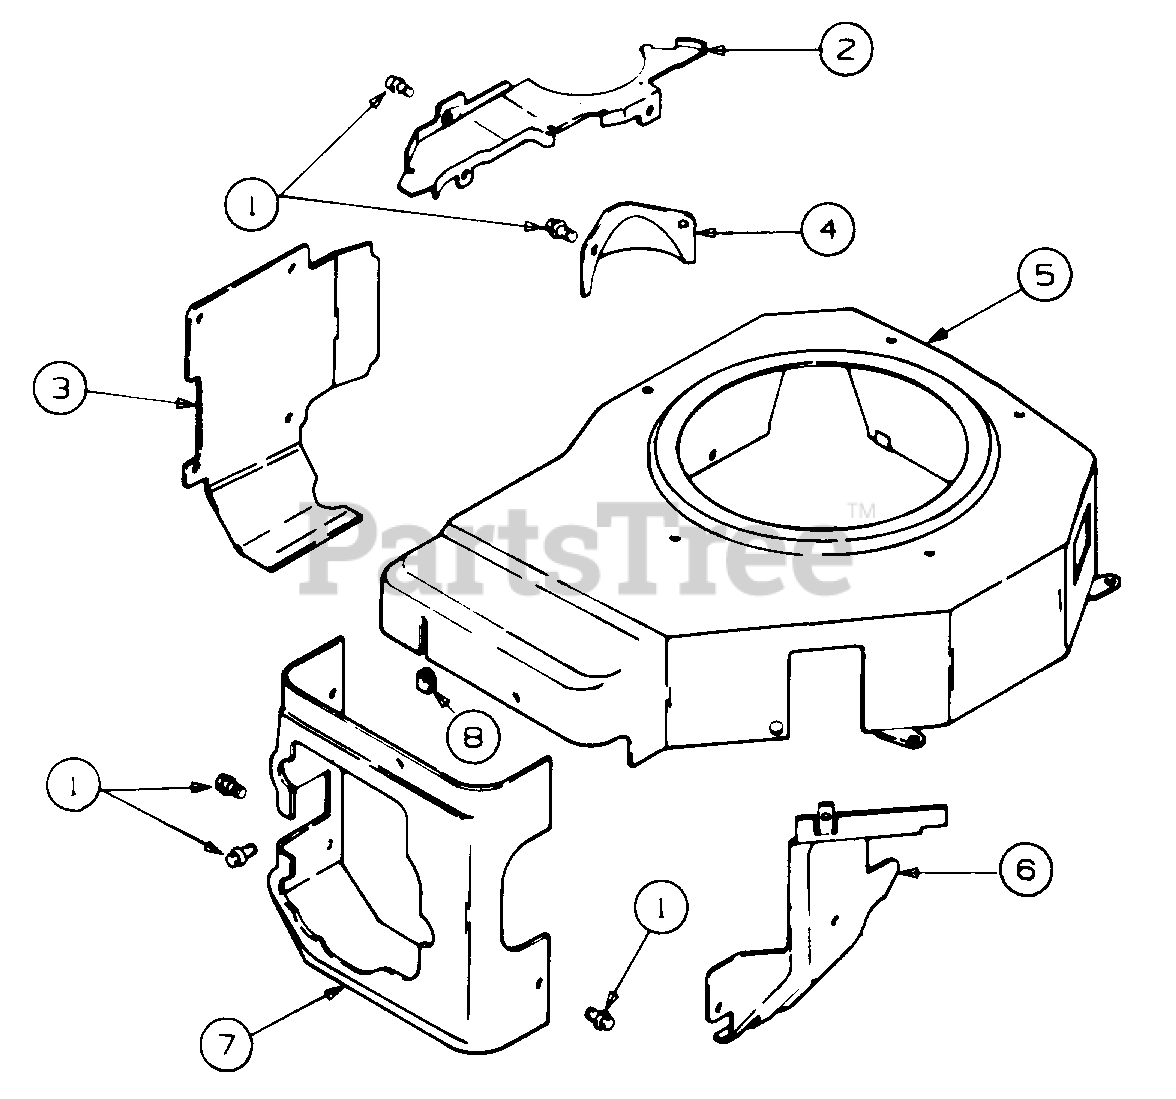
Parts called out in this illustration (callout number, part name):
1	Screw, Mounting, M5 X 0.8 X 10
2	Plate, Blower Housing
3	Baffle, Cylinder Barrel
4	Cover, Starter
5	Housing, Blower
6	Baffle, Carburetor
7	Baffle, Cylinder Head
8	Grommet, Blower Housing
